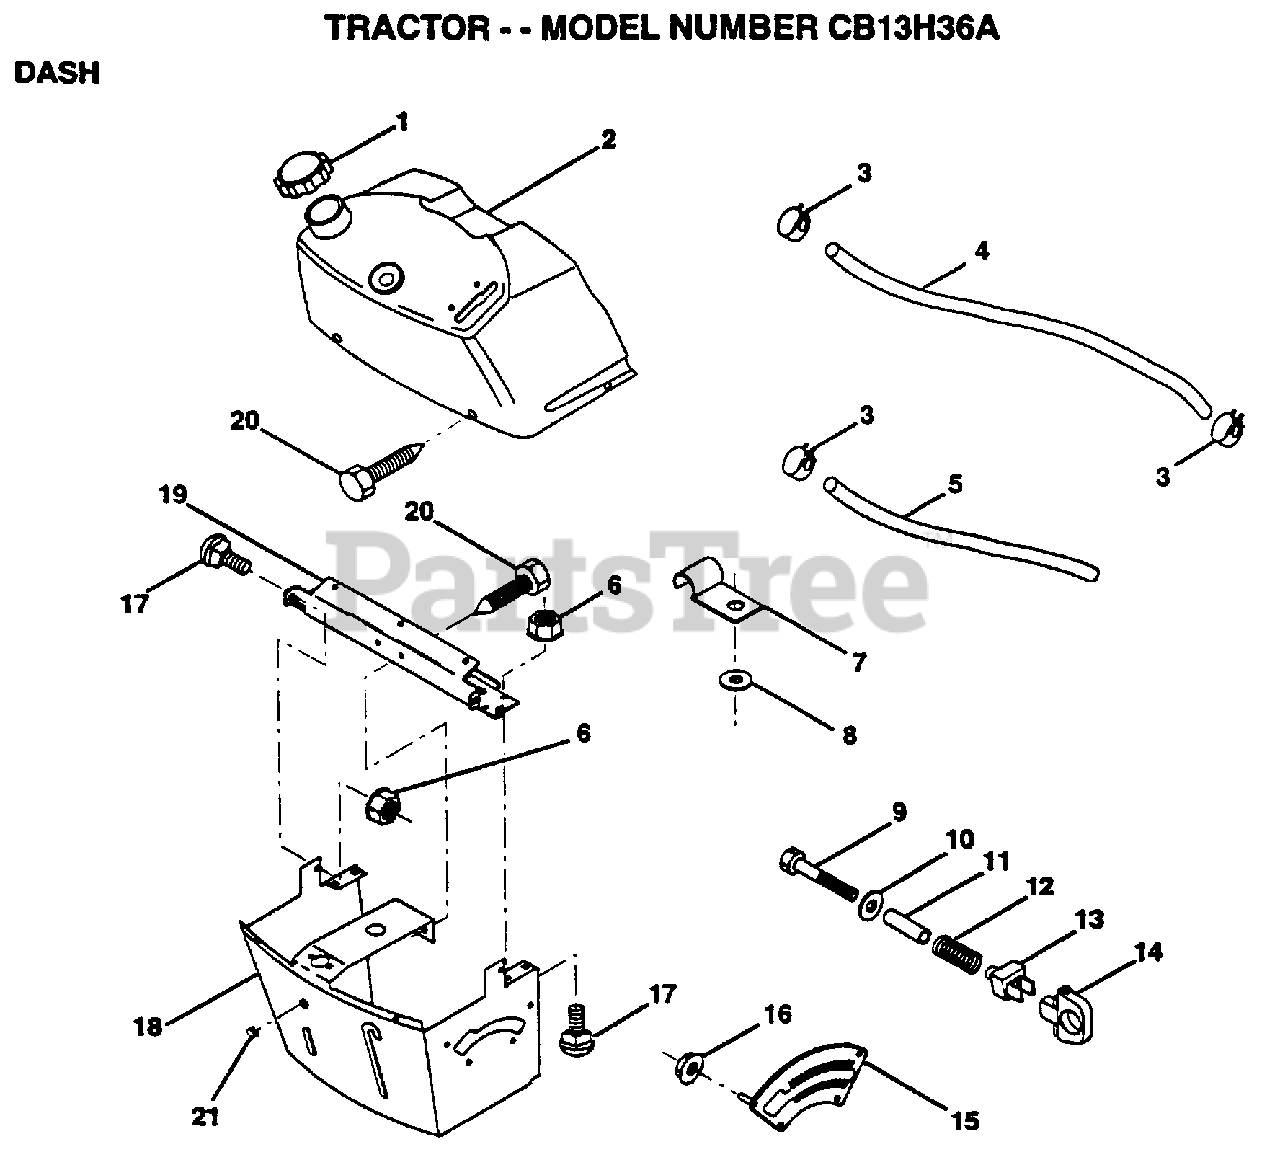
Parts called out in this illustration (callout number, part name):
1	CAP BLK FUEL LR
2	TANK.ASM.DASH.LR
3	HOSE CLAMP
5	FUEL LINE T
6	NUT HXKEP 1/4X20
7	CLIP T
8	WASHER PM
9	BOLT
11	SPACER SPLIT
12	SPRING M
13	"KNOB,HGT RETAINER"
14	KNOB
15	ADJUSTER QUAD
16	NUT
17	BOLT
18	SUPT ASSY DASH
19	CROSS BRACE
20	SCREW.1/4-20X1/2
21	PLUG DOME
